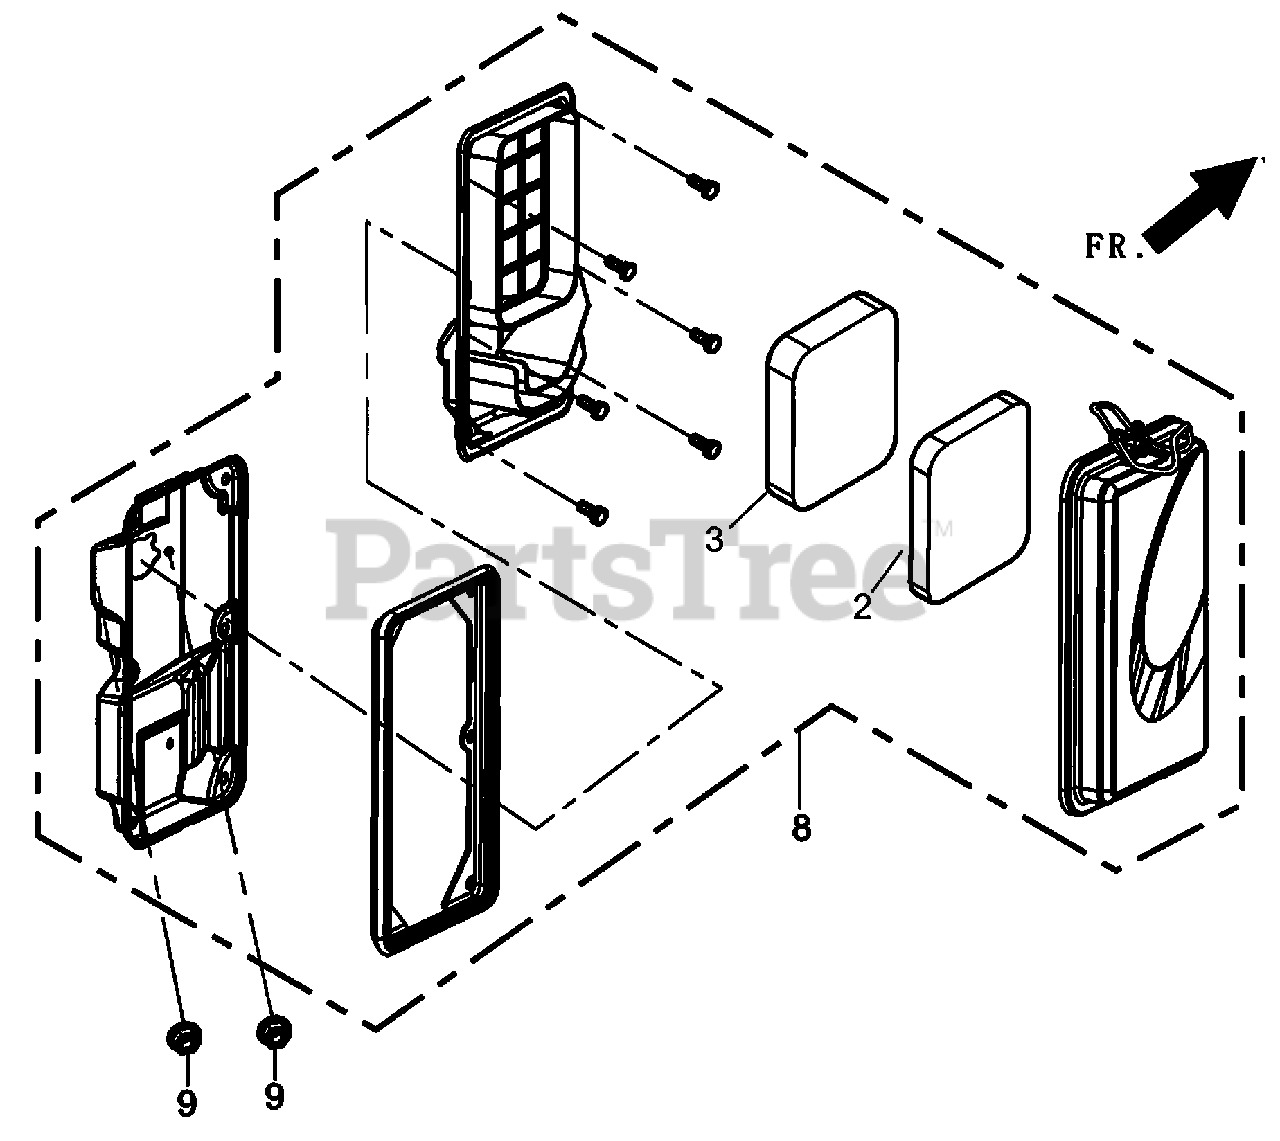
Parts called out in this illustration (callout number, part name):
2	ELEMENT, AIR CLEANER
3	ELEMENT, AIR CLEANER
8	CLEANER, AIR
